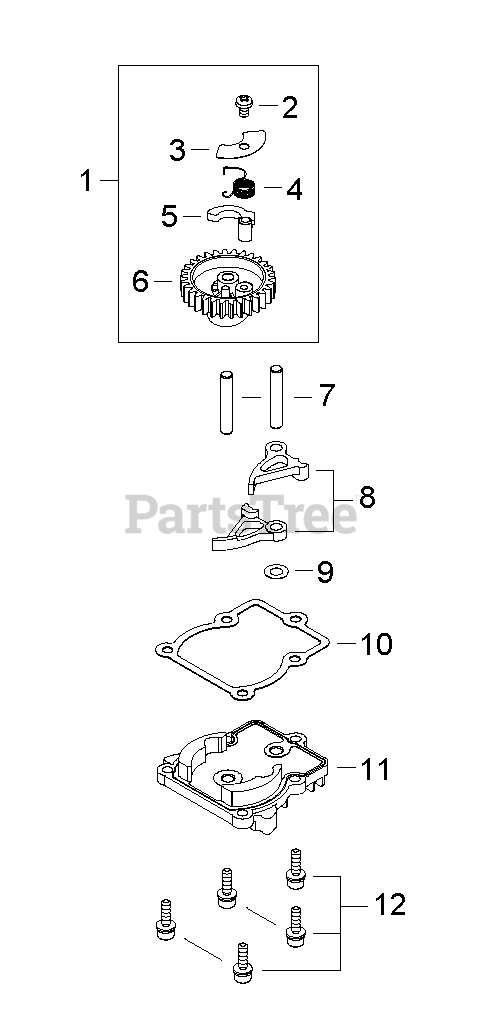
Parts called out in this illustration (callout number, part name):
1	CAM GEAR ASSY
2	SCREW - 4X6 -- TAPPING
3	COVER, PLATE
4	SPRING
5	WEIGHT
6	GEAR, CAM
7	PIN - LOCATING
8	FOLLOWER, CAM
9	WASHER - 5
10	GASKET
11	COVER, CAM GEAR
12	SCREW - 4X14
